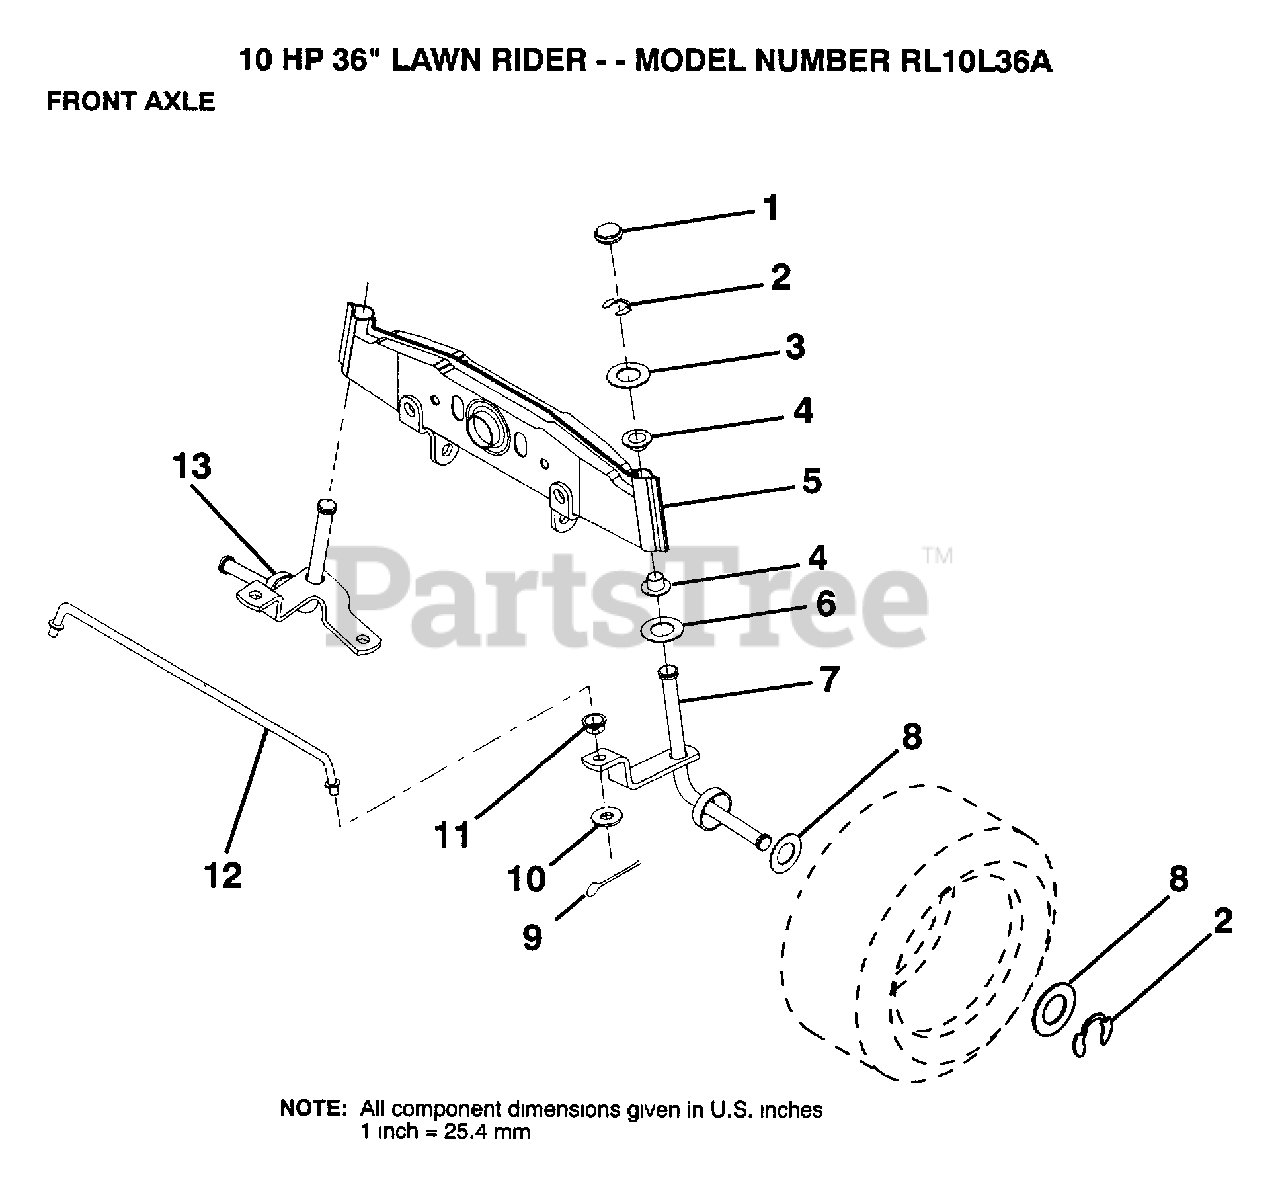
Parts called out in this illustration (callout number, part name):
1	CAP
2	RING
3	WASHER
4	NYLINER
5	AXLE FRONT
6	WASHER .T
7	SPINDLE RH
8	WASHER
9	COTTER PIN
10	WASHER
11	BUSHING.DRAGLINK
12	ROD TIE
13	SPINDLE LH
